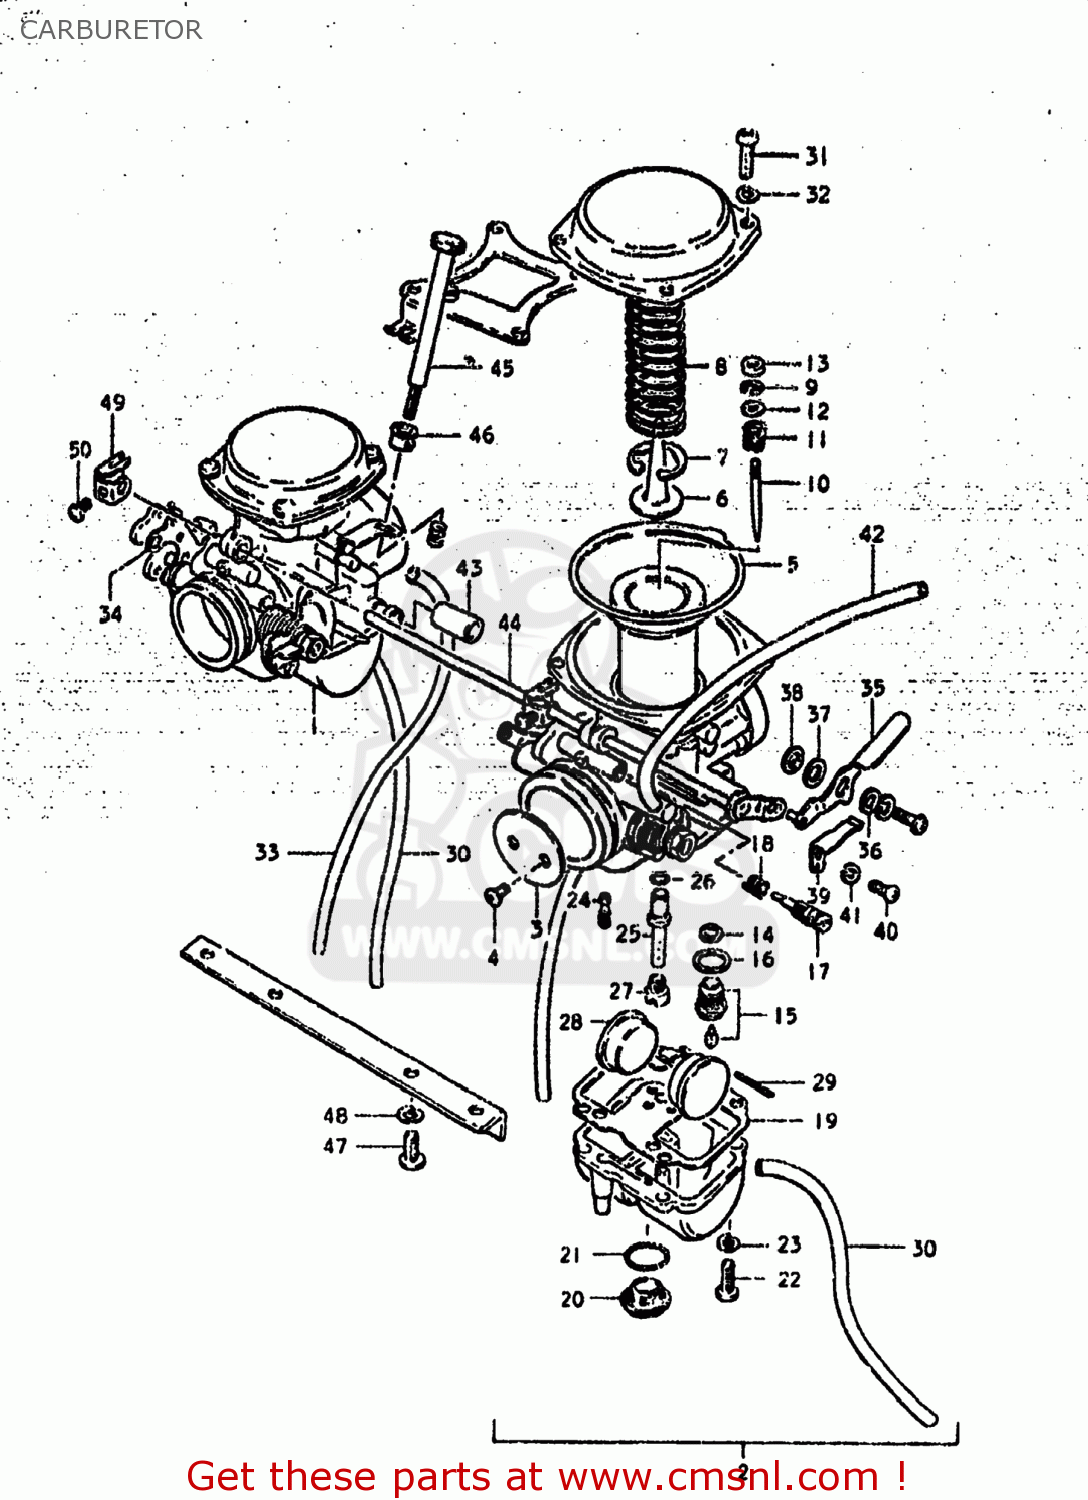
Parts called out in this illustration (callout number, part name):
1	CARBURETOR ASSEMBLY
2	CARBURETOR ASSEMBLY
3	VALVE,THROTTLE
4	SCREW
5	DIAPHRAGM ASSEMBLY
6	HOLDER,GUIDE
7	E RING
8	SPRING,DIAPHRAGM
9	CLIP
10	NEEDLE JET
11	SPRING
12	WASHER
13	RING
14	FILTER
15	VALVE ASSY,NEEDLE
16	GASKET,MAIN JET HOLDER (NAS)
17	SCREW,PILOT AIR
18	SPRING,THROTTLE SCREW
19	GASKET,FLOAT CHAMBER (NAS)
20	SCREW,GUIDE
21	O-RING
22	SCREW
23	LOCK WASHER
24	JET,PILOT
25	JET,NEEDLE
26	O-RING
27	SET, MAIN
28	FLOAT
29	PIN,FLOAT
30	HOSE
31	SCREW
32	LOCK WASHER
33	HOSE
34	GASKET
35	LEVER
36	WASHER,STARTER LEVER
37	WASHER,STARTER LEVER
38	RING,STARTER LEVER
39	SPRING
40	SCREW
41	LOCK WASHER
42	HOSE
43	HOSE
44	SHAFT,STARTER
45	ADJUSTER
46	BUSH
47	SCREW 6X12
48	LOCK WASHER
49	LEVER, STARTER
50	SCREW
